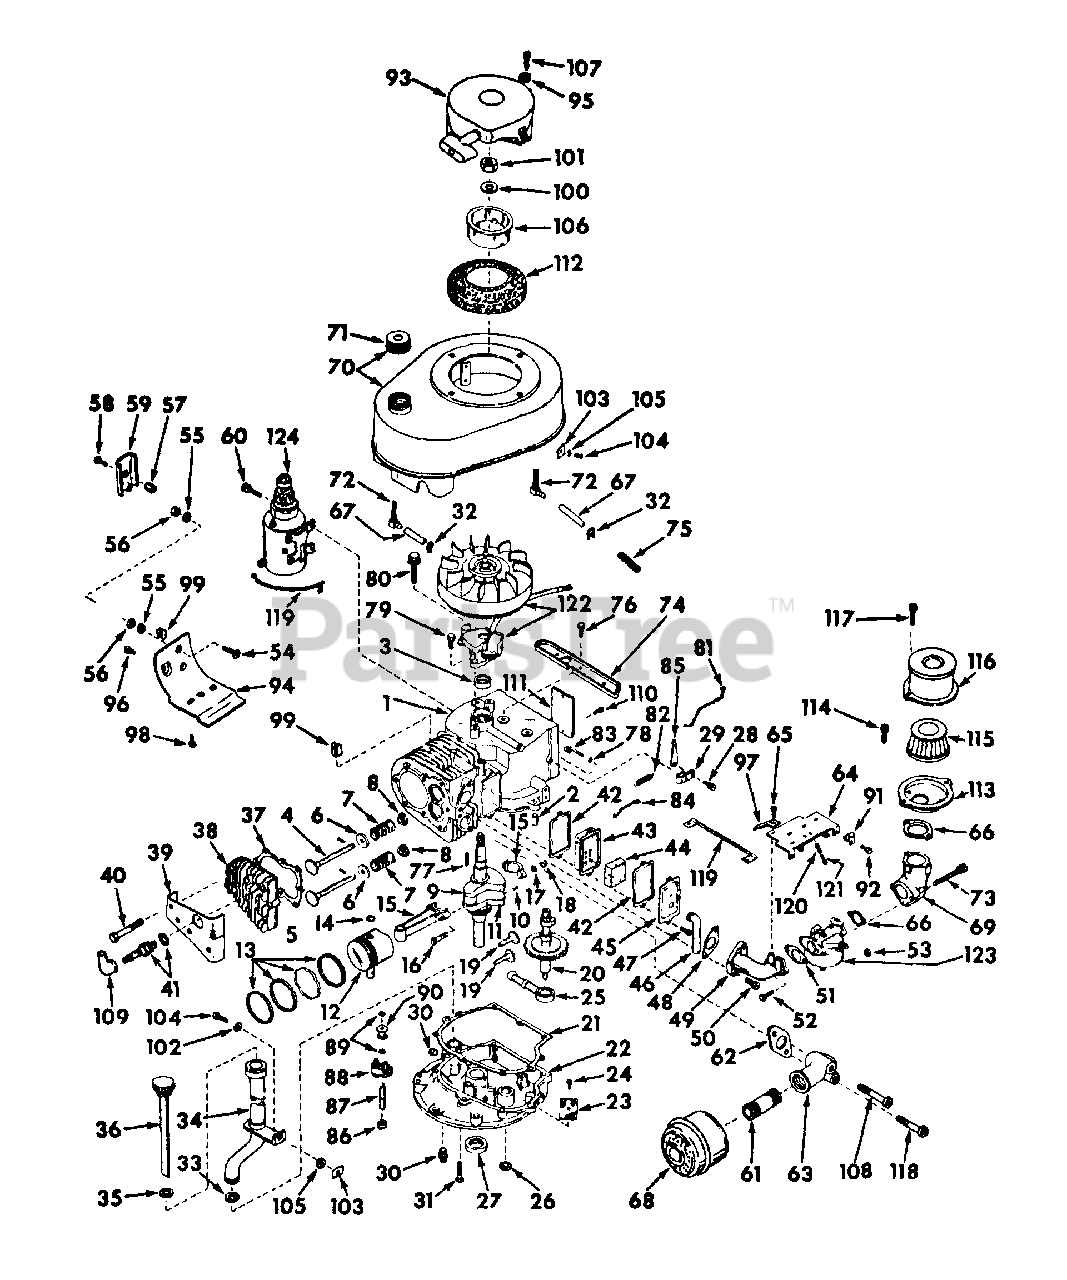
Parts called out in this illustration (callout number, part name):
1	BLOCK ASSY, SHORT
2	PIN, DOWEL
4	VALVE, INTAKE - STD
5	VALVE, EXHAUST - STD
6	CAP, UPPER VALVE SPRING
7	SPRING, VALVE
8	CAP, LOWER VALVE SPRING
9	CRANKSHAFT ASSY
10	SPIN, CRANKSHAFT GEAR
11	GEAR CRANKSHAFT
12	PISTON AND PIN ASSY, STD
13	RING SET, PISTON - STD
13	RING SET, PISTON - #10 OVERSIZE
14	RING, PISTON PIN RETAINING
15	ROD ASSY, CONNECTING
16	BOLT, CONNECTING ROD
17	WASHER, 11/32 X 9/16 X 16 GA
18	NUT, 5/16-24 HEX
19	VALVE, LIFTER
20	CAMSHAFT ASSY
21	GASKET, MOUNTING FLANGE
22	FLANGE ASSY, MOUNTING
23	SCREEN, OIL FILTER
24	SCREW, 8-32 X 5/16 HEX-HD
25	PUMP ASSY, OIL
28	SCREW, 8-32 X 3/8 HEX. WASHER HD
29	CLAMP, GOVERNOR LEVER
30	PLUG, 1/4 MALL C-Z SQ-HD PIPE
31	SCREW, 1/4-20 X 1-1/4 HEX-HD
33	O-RING, 5/8 X 3/4 X 1/16
34	TUBE, OIL FILLER
35	O-RING, 1 X 1-1/4 X 1/8
36	PLUG AND GAUGE ASSY, OIL
37	GASKET, CYLINDER HEAD
38	HEAD, CYLINDER
39	COVER, CYLINDER
40	SCREW, 5/16-18 X 2-1/2 HEX-HD CAP
41	PLUG, SPARK -CHAMPION-
42	GASKET, VALVE CHAMBER COVER
43	BODY, BREATHER
44	ELEMENT, BREATHER
45	COVER, VALVE CHAMBER
46	TUBE, BREATHER
47	SCREW AND LOCKWASHER ASSY
48	GASKET, INTAKE PIPE
49	PIPE, INTAKE
50	SCREW W/LOCKWASHER, 5/16-18 X 1-1/8 CR-REC-FIL-HD
51	GASKET, CARBURETOR
52	SCREW, 1/4-28 X 7/8 C-Z HEX-HD CAP
53	NUT AND WASHER ASSY
54	SCREW, 5-40 X 9/16 C-Z CR-REC-PAN-HD MACH
55	WASHER, NO. 5 HV LOCK
56	NUT, 5-40 C-Z HEX MACH SCREW
57	NUT, LONG
58	SCREW, 5-40 X 3/8 SLT-RD-HD MACH
59	COVER, RECTIFIER PANEL
60	SCREW AND LOCK WASHER ASSY
61	NIPPLE, 3/4 X 2-1/2 PIPE
63	ELBOW, EXHAUST
64	CONTROL ASSY, SPEED
65	SCREW AND LOCKWASHER ASSY
66	GASKET, AIR CLEANER
69	ELBOW, AIR CLEANER
70	TANK ASSY, FUEL
71	CAP, FUEL
72	FITTING, STRAINER AND ELBOW
73	SCREW W/SPRING, LOCK WASHER
74	BRACKET, BLOWER HOUSING
75	SPRING, COIL
76	SCREW W/EXT TOOTH LOCK WASHER, 1/4-20 X 5/8 HEX-HD MACH
77	KEY, FLYWHEEL
78	WASHER, FLAT
79	SCREW AND WASHER ASSY
80	SCREW AND WASHER
81	LINK, THROTTLE
82	SPRING, GOVERNOR
83	ROD, GOVERNOR
84	LINK, GOVERNOR SPRING
85	LEVER, GOVERNOR
86	SPACER
87	SHAFT, MECHANICAL GOVERNOR
88	GEAR ASSY, GOVERNOR
89	RING, RETAINING
90	SPOOL, GOVERNOR
91	CLIP, CONDUIT
92	SCREW W/EXT TOOTH LOCK WASHER, 10-32 X 3/8 HEX-HD MACH
93	STARTER ASSY REWIND
94	EXTENSION, BLOWER HOUSING
95	WASHER, 17/64 X 1/2 X 16 GA
96	SCREW AND LOCK WASHER ASSY
97	CLIP, FUEL LINE
98	SCREW AND LOCK WASHER ASSY
99	CLIP, HI-TENSION WIRE RETAINING
100	WASHER, BELLEVILLE
101	NUT, 1/2-20 HEX.
102	WASHER, 11/32 X 9/16 X 16 GA
103	PLATE, SECURING
104	SCREW, 5/16-24 X 3/4 C-Z SLT-FIL-HD MACH
105	WASHER, 5/16 C-Z MED LOCK
106	CUP, STARTER
107	SCREW W/EXT TOOTH LOCK WASHER
108	SCREW, 5/16-18 X 2-1/4 HEX-HD CAP
109	COVER, SPARK PLUG
110	SCREW, NO. 4 X 5/16 C-Z RD-HD BLUNT METAL DRIVE
111	PLATE, IDENTIFICATION
112	SCREEN, STARTER CAP
113	BRACKET, AIR CLEANER
114	SCREW W/SPRING LOCK WASHER
115	ELEMENT, CLEANER
116	BODY, AIR CLEANER
117	SCREW, 8-32 X 3/8 C-Z FIL-HD MACH
118	SCREW, 5/16-18 X 2-3/4 HEX-HD CAP
119	WIRE, GROUND
120	SPRING, COMPRESSION
121	SCREW, 5-40 X 7/16 C-Z FIL-HD MACH
122	MAGNETO
123	CARBURETOR ASSY
124	MOTOR, STARTER
